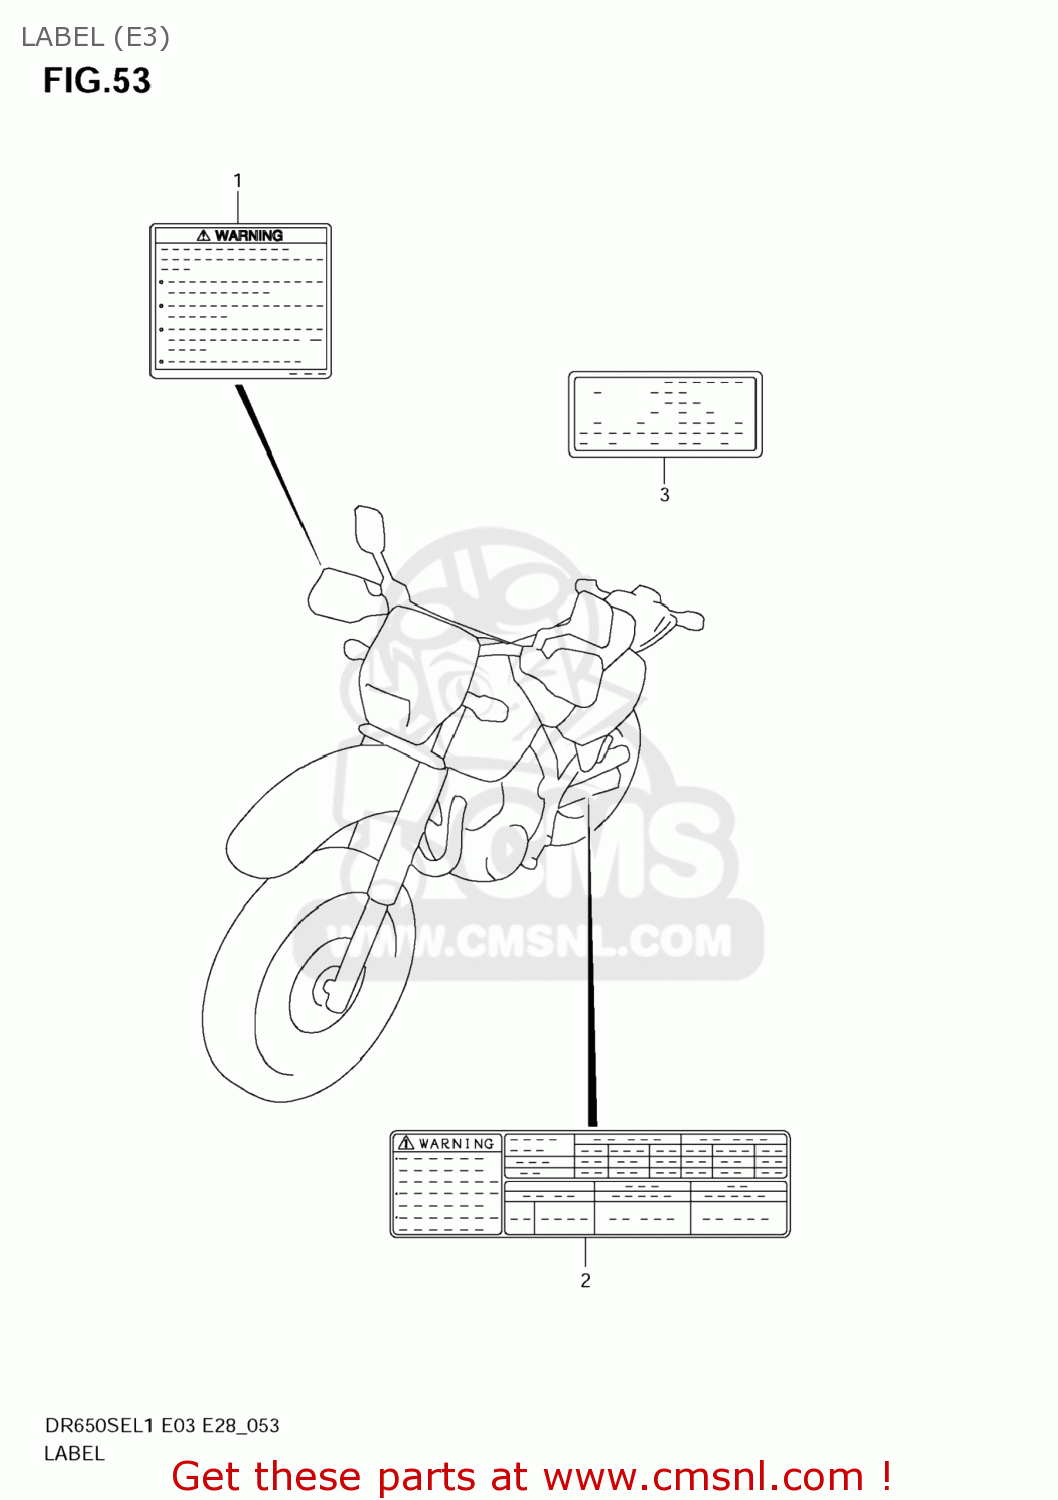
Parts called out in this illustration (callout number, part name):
1	LABEL,GENERAL WARNING
2	LABEL,TIRE INFORMATION
3	LABEL,MANUAL NOTICE
4	MANUAL,OWNER'S
